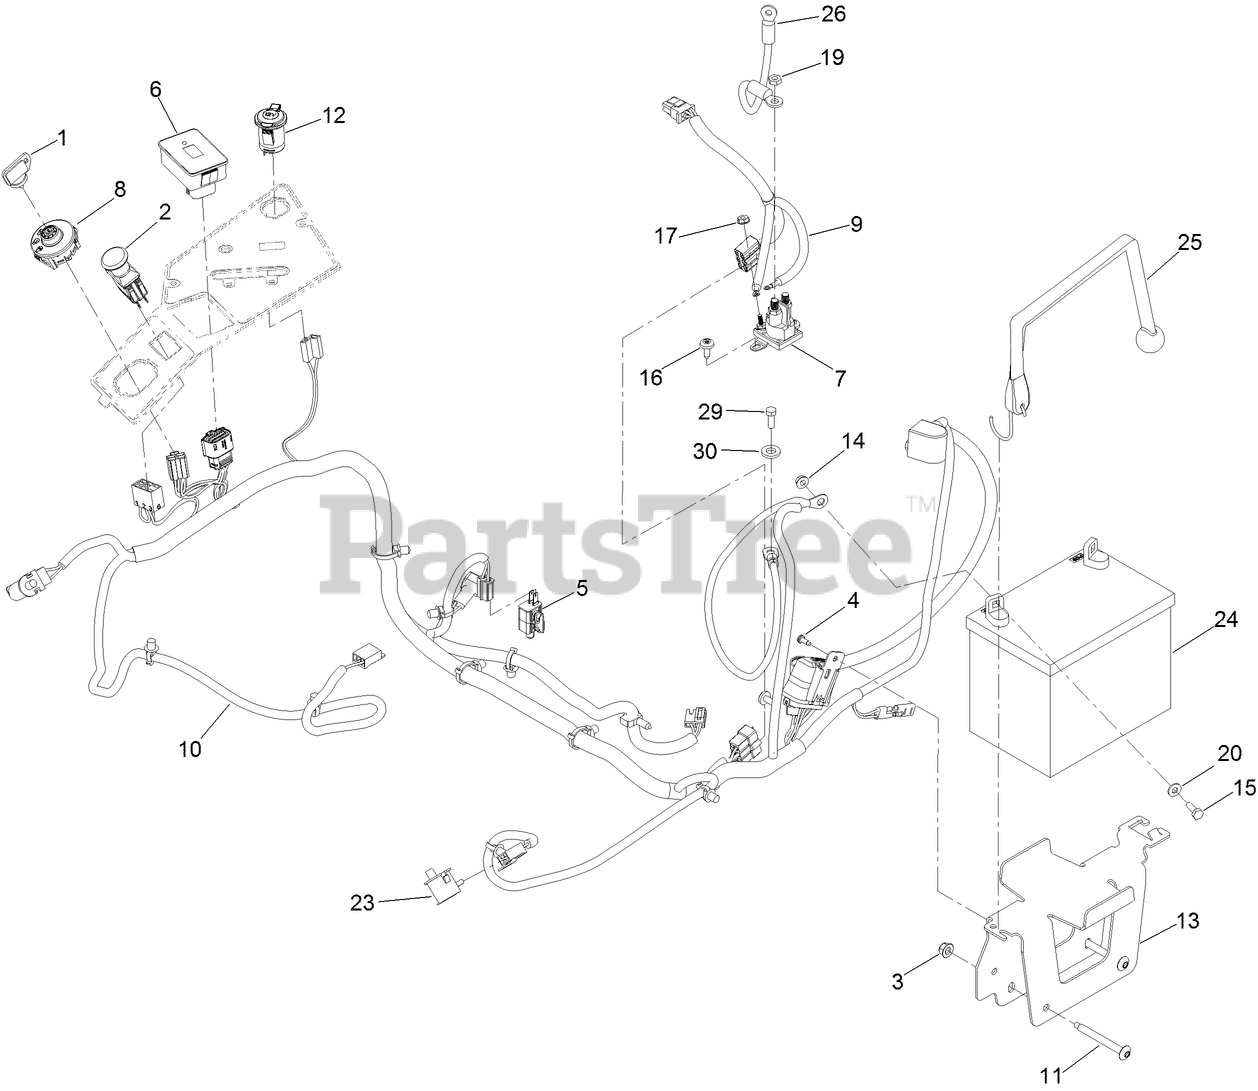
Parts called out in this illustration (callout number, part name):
1	KEY-IGNITION
2	SWITCH-PTO
3	NUT-HF, NI
4	SCREW-FORMING, THREAD
5	SWITCH
6	MODULE ASM
7	SOLENOID
8	SWITCH-IGNITION
9	ADAPTER-HARNESS, WIRE
10	HARNESS-WIRE
11	SCREW-TORX
12	PORT-POWER, 12V
13	TRAY-BATTERY
14	NUT-HF
15	SCREW-HH
16	SCREW-TORX
17	NUT-KEPS
19	NUT-JAM
20	WASHER-FLAT
23	SWITCH-BAIL
24	BATTERY (300 CCA, WET)
25	STRAP-BUNGEE
26	CABLE-BATTERY, POSITIVE
